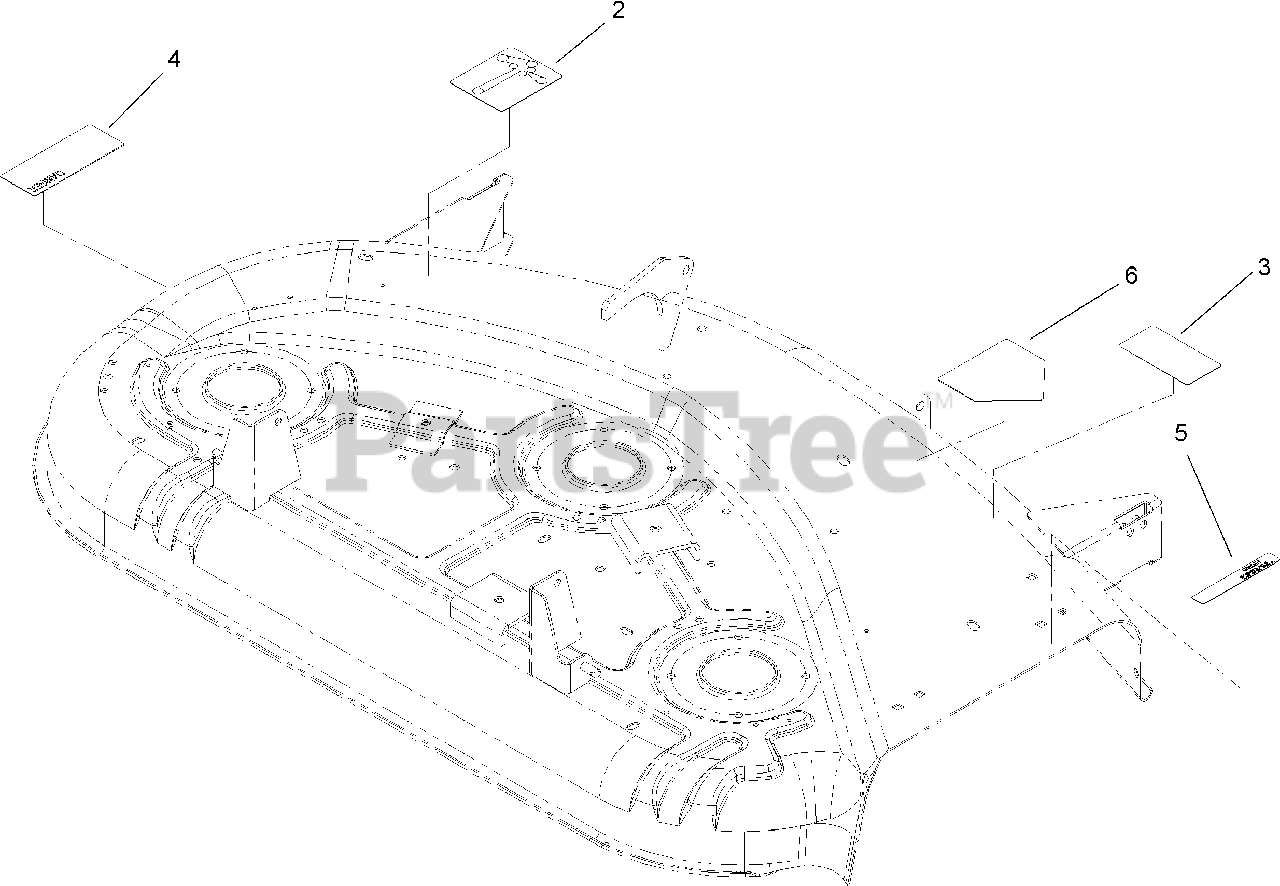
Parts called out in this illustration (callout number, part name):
2	DECAL-ROUTING, BELT
3	DECAL-WHEEL ADJUSTMENT
4	DECAL-DANGER
5	DECAL-CAUTION
6	DECAL-DANGER
